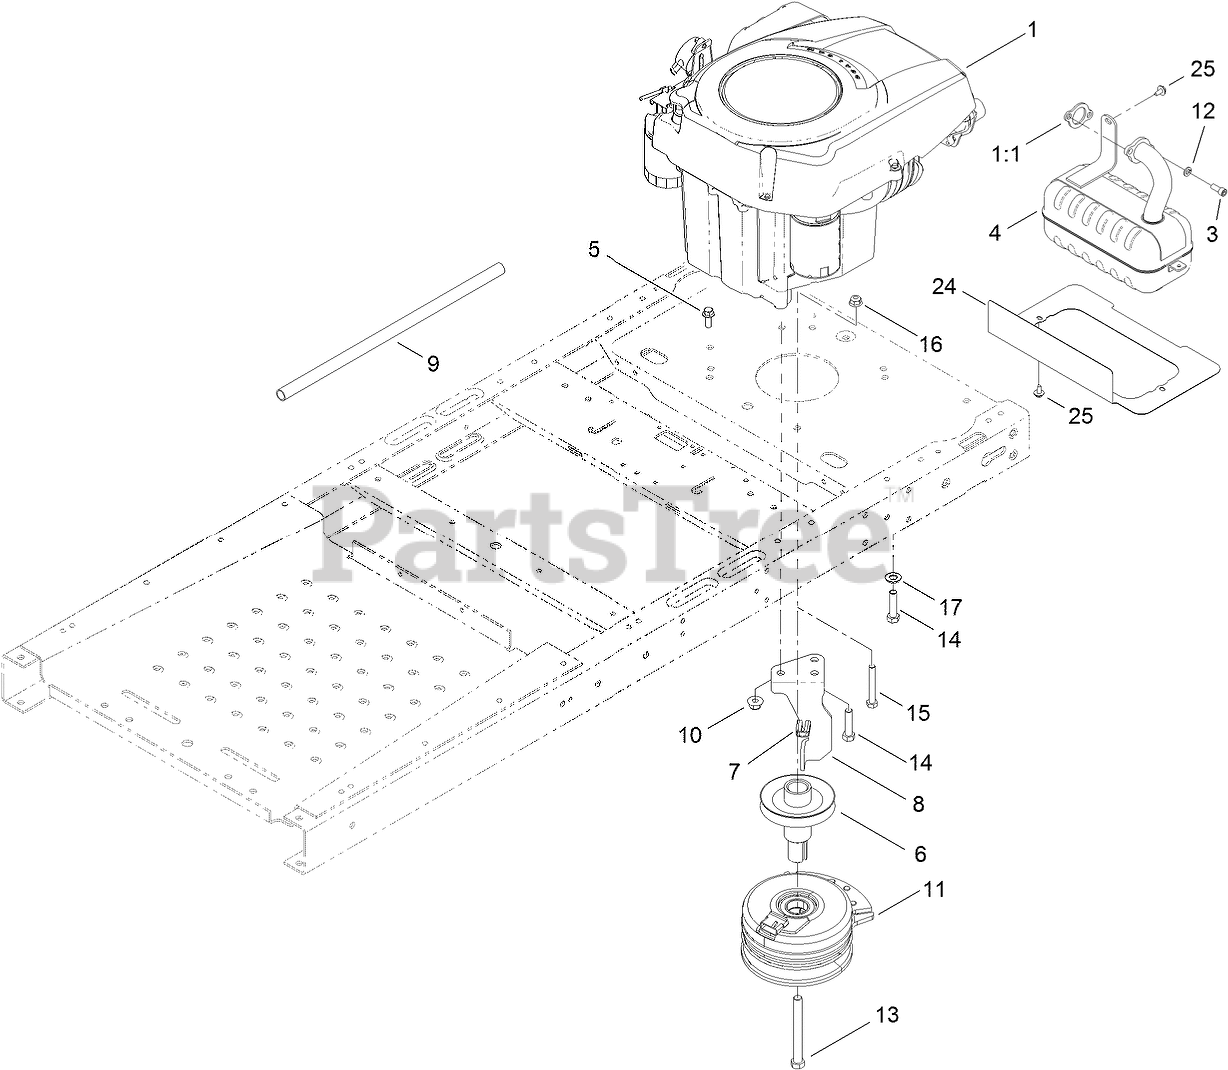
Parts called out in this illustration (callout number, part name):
1:1	GASKET-EXHAUST
3	SCREW-HSH
4	MUFFLER-KOHLER
5	SCREW-HHF
6	PULLEY-ENGINE
7	ISOLATOR-CLUTCH
8	STOP-CLUTCH
9	TUBE-DRAIN, OIL
10	NUT-HF, NI
11	CLUTCH-ELECTRIC
12	WASHER-LOCK
13	SCREW-HH
14	SCREW-TAPTITE
15	SCREW-HH
16	NUT-HF, NI
17	WASHER-FLAT
24	SHIELD-HEAT
25	SCREW-HHFTF
